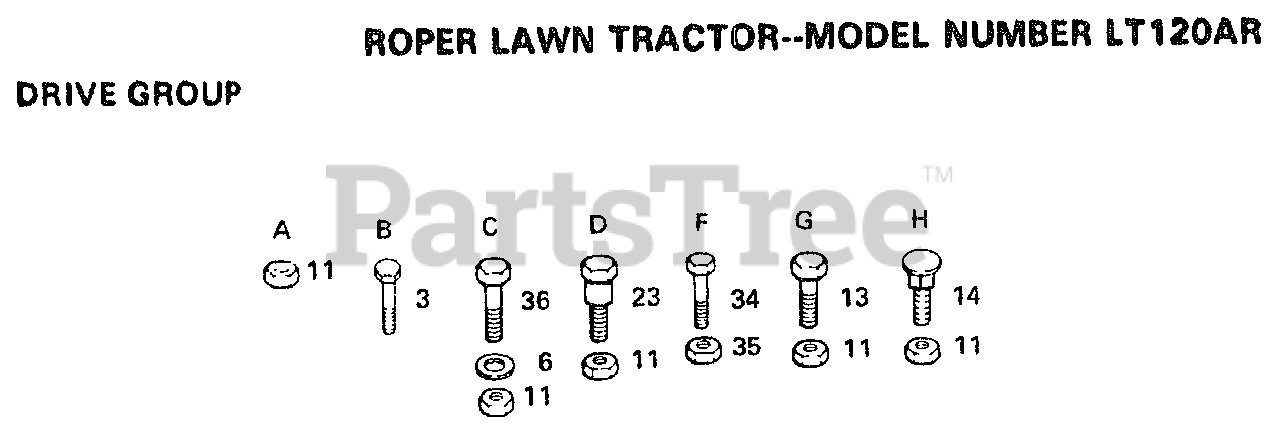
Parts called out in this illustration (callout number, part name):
3	SCREW
6	WASHER
14	BOLT
23	"BOLT, SHOULDER LT"
34	BOLT
36	BOLT
